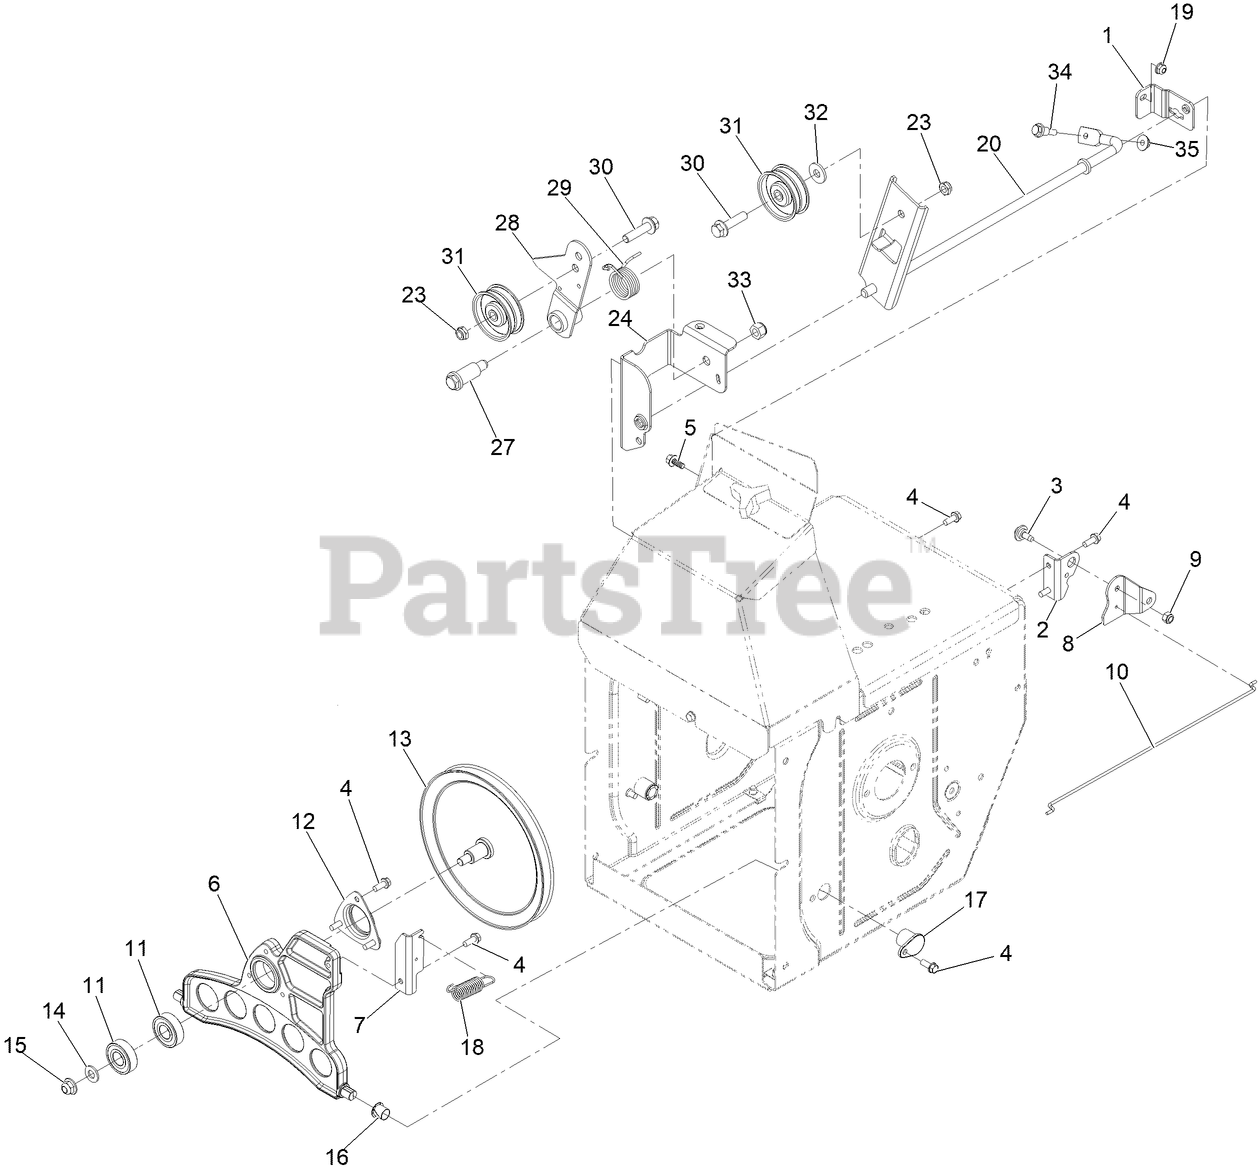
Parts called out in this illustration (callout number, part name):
1	BRACKET-CLUTCH, IMPELLER
2	X-REF TO 136-6654-03
3	SCREW-SHOULDER
4	SCREW-HWH
5	Screw-HHF 1/4-20 X 5/8
6	PLATE-FRICTION, WHEEL
7	Bracket-Plate, Traction
8	BELLCRANK-DRIVE
9	NUT-HEX
10	LINK-DRIVE
11	BEARING-BALL
12	RETAINER-BEARING
13	PULLEY-TRACTION
14	WASHER-FLAT
15	Nut-HF, NI
16	BUSHING-NYLINER
17	BUSHING-PLATE, TRACTION
18	SPRING-EXTENSION
20	Arm-Clutch, Impeller
23	NUT-HEX
24	BRACKET-BRAKE, CLUTCH
27	BOLT-SHOULDER
28	ARM-IDLER, TRACTION
29	SPRING-TORSION
30	SCREW-HHF
31	PULLEY-IDLER
32	WASHER-HARDENED
33	Nut-Hex
34	Bolt-Shoulder
